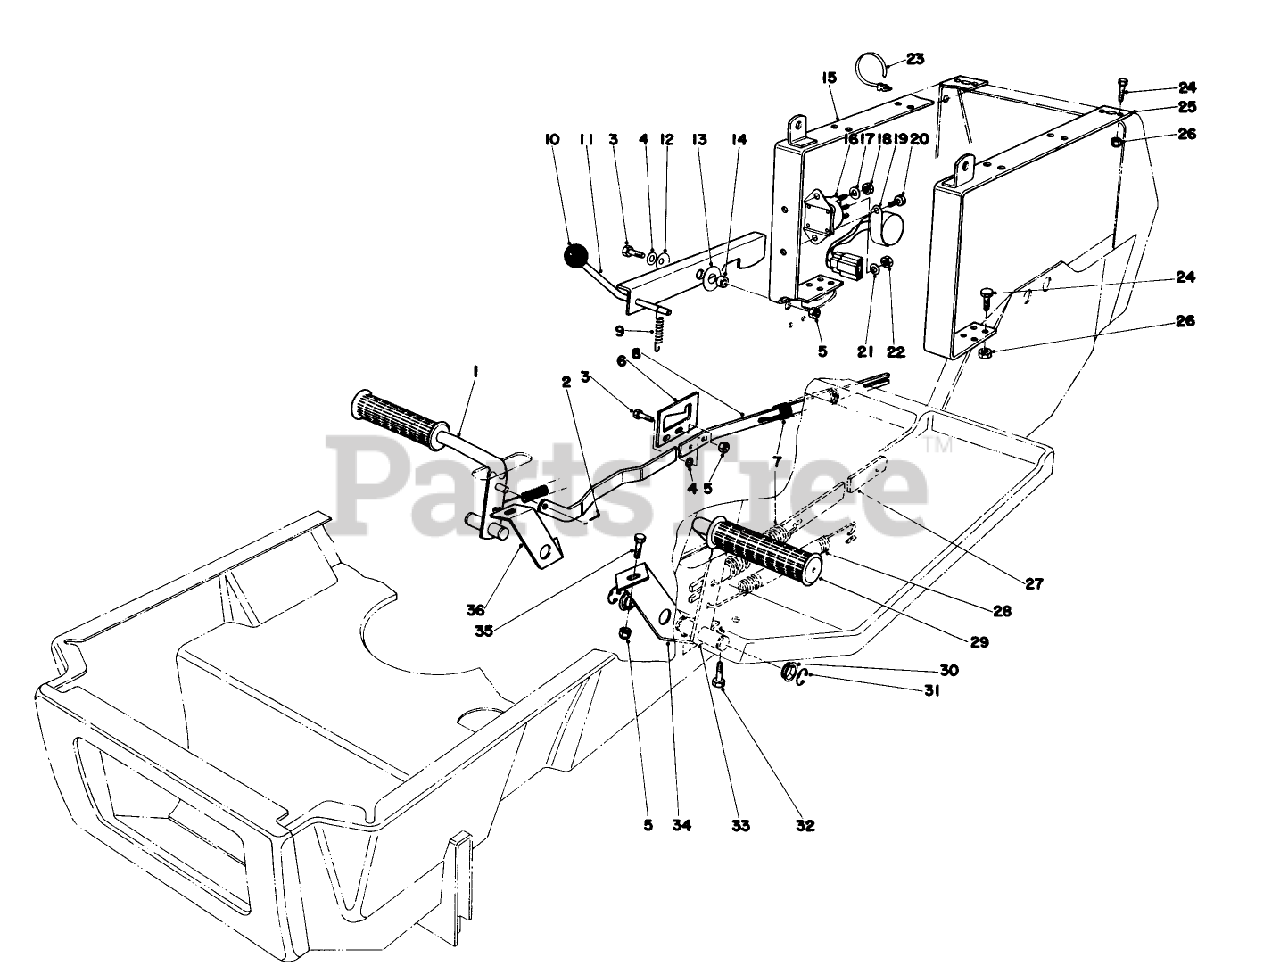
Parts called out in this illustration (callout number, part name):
1	BRAKE PEDAL WA BO
2	PIN-COTTER
3	SCREW-HH
4	WASHER-PLAIN
5	NUT-LOCK, CONE
6	LATCH PLT-BRAKE ROD
7	EXT SPRING O
8	LINK BRAKE ROD WAB
9	CONT ROD SPRING 0
11	PARKING BRAKE WA B
12	WASHER-BELLEVILLE
13	WASHER-PLASTIC
14	SPACER
15	RR BODY STRAP WA B
16	SOLENOID
17	WASHER-LOCK
18	NUT-JAM, BRASS
19	Module Interlock
20	SCREW-HWH
21	WASHER-LOCK
22	NUT-HEX
23	TIE-MOUNT, PUSH
24	SCREW-HH
25	LH RR BODY STRAP WA B
26	NUT-LOCK, CONE
27	CLUTCH ROD LINK B
28	SPRING-EXTENSION
29	FOOT PAD
30	Nyliner
31	E-RING
32	SCREW-HWHTF
33	CLUTCH PEDAL WA BO
34	LH PEDAL SUPT B
35	SCREW-HH
36	RH PEDAL SUPT B
